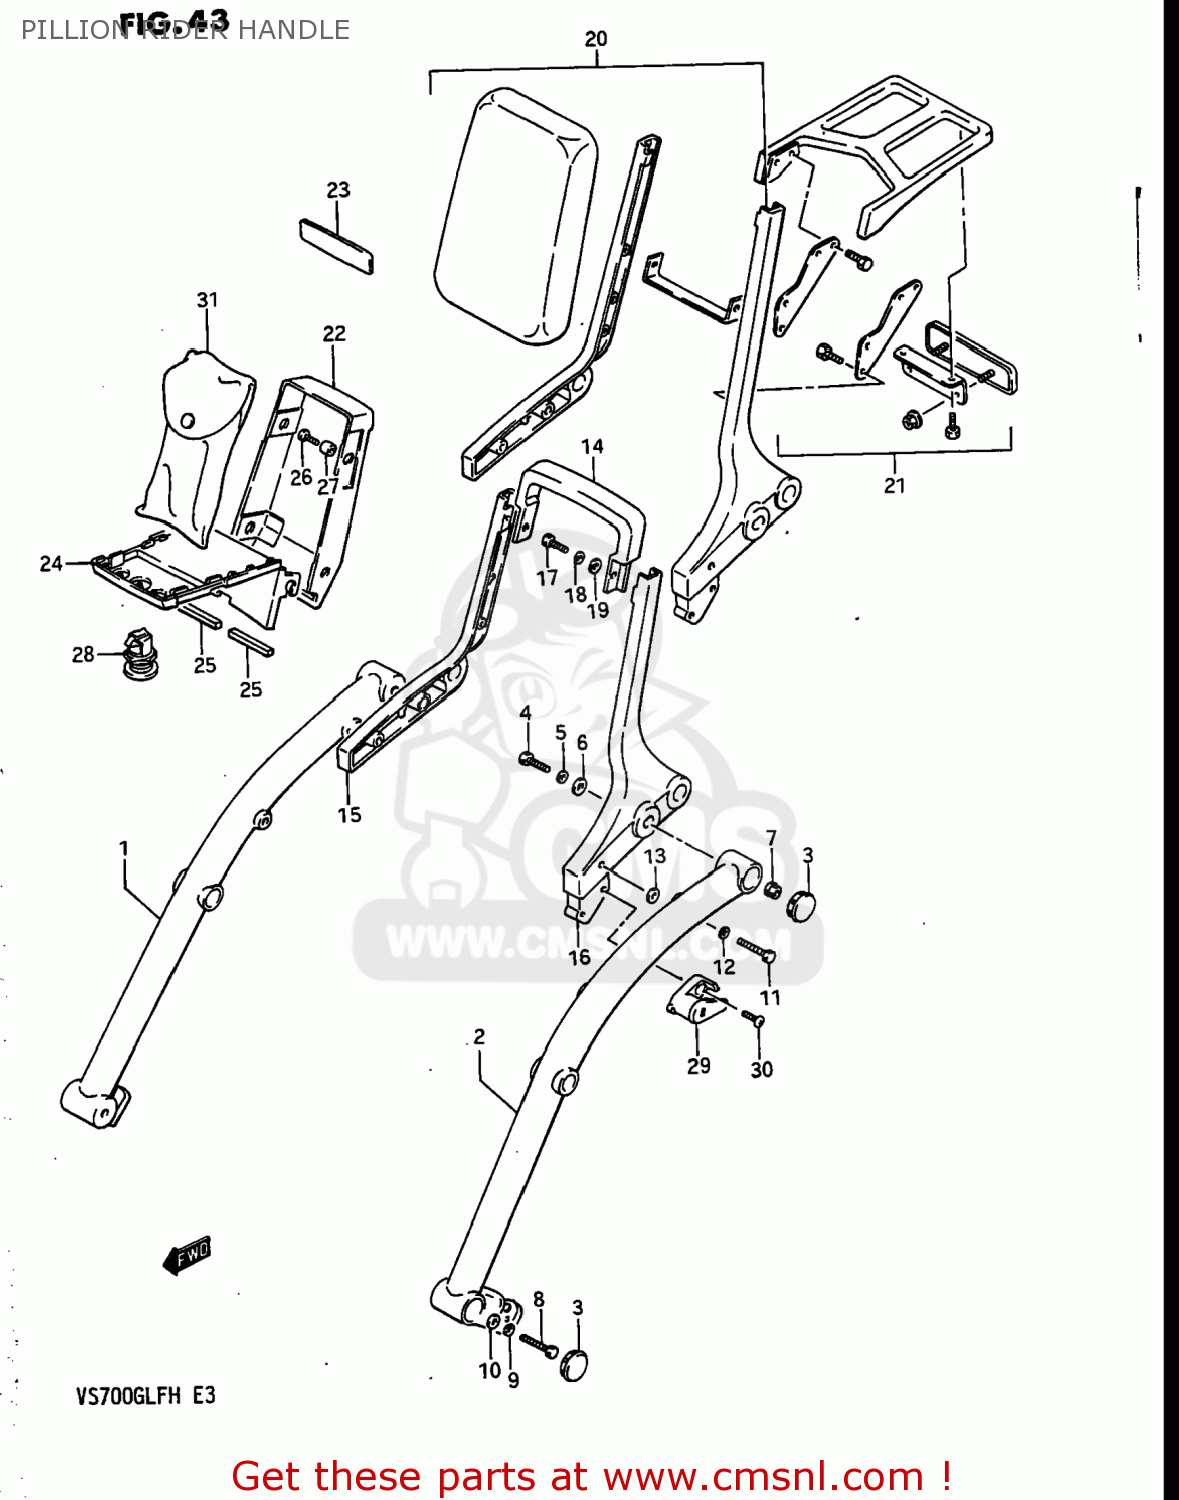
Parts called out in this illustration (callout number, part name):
1	GRIP,FRAME HANDLE
2	GRIP,FRAME HANDLE,LEFT
3	CAP,FRAME HANDLE GRIP
4	BOLT
5	LOCK WASHER
6	WASHER
7	NUT, WHEEL SET
8	BOLT ,6X35
9	WASHER,LOCK
10	WASHER, LOWER
11	BOLT,FRONT
12	WASHER,LOCK,8.
13	WASHER
14	HANDLE,PILLION RIDER,U
15	HANDLE,PILLION RIDER
16	HANDLE,PILLION RIDER
17	BOLT
18	WASHER,LOCK
19	WASHER
20	HANDLE SET,PILLION RIDER
21	CARRIER ASSEMBLY,SUPPORT
22	HOLDER,TOOL
23	EMBLEM,TOOL HOLDER,REAR
24	HOLDER,TOOL FR
25	CUSHION,TOOL HOLDER
26	SCREW
27	SPACER
28	LOCK SET,TOOL HOLDER
29	LOCK SET
30	SCREW
31	TOOL ASSY
